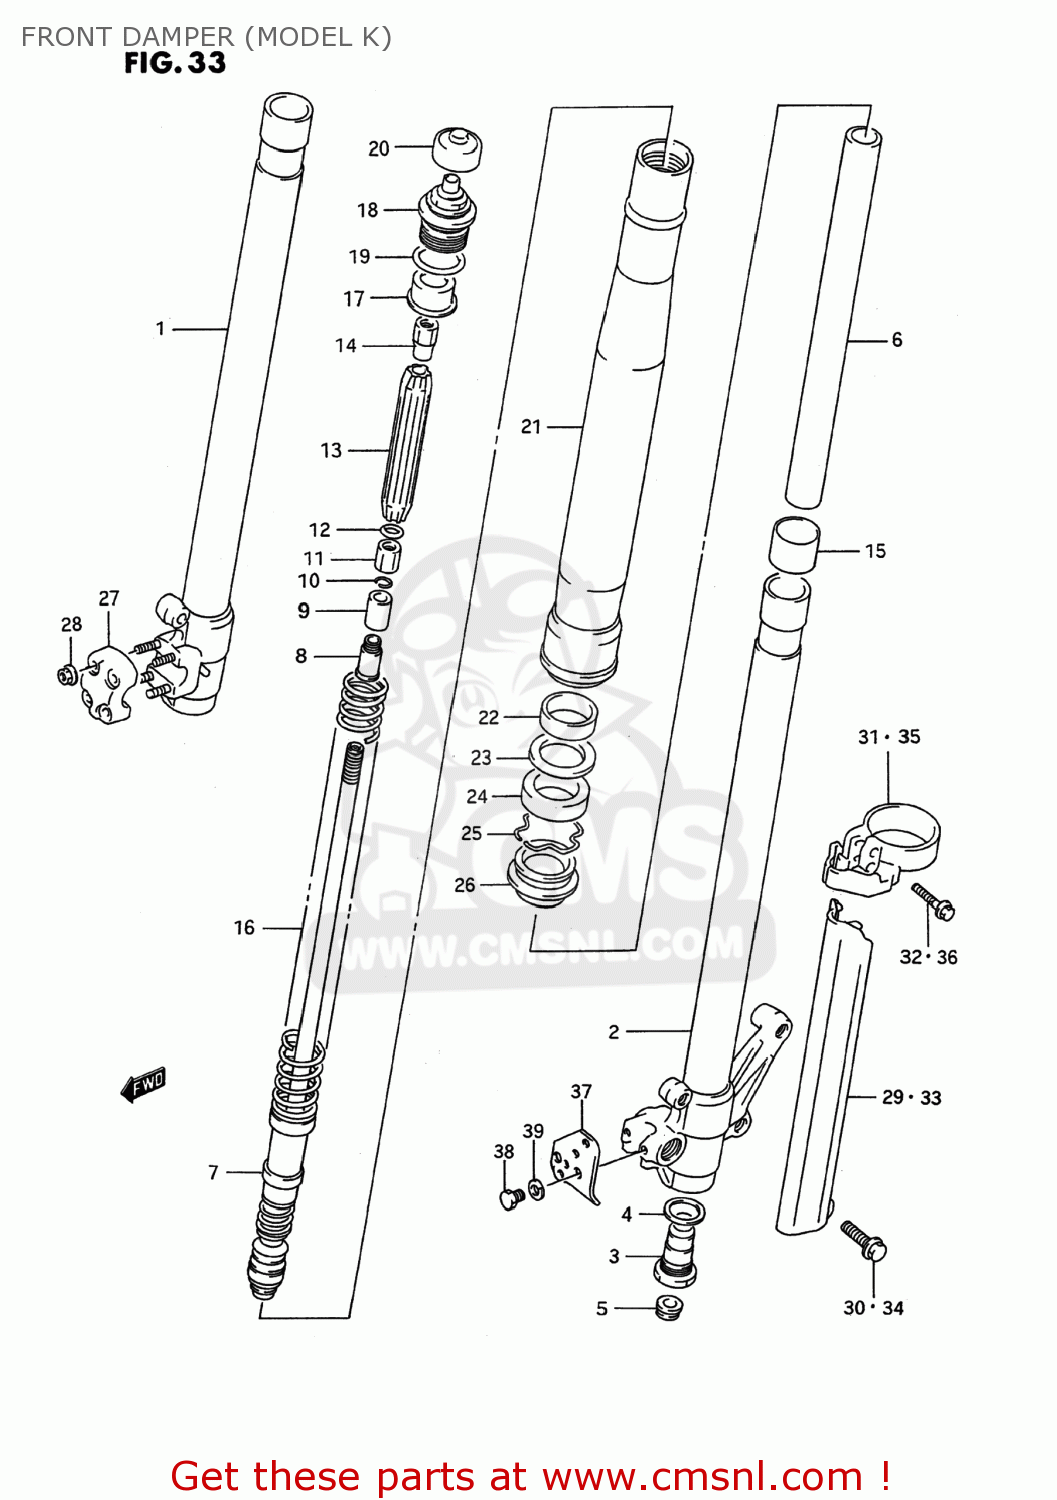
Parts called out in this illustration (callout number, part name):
1	TUBE,INNER,RIGHT
2	TUBE,INNER,LEFT
3	BASE,VALVE ASSEMBLY
4	GASKET (NAS)
5	CAP,RUBBER
6	CYLINDER
7	ROD ASSEMBLY,PISTON
8	HOLDER,PIECE
9	PIECE,OIL LOCK
10	RING,SNAP
11	NUT
12	O-RING
13	GUIDE,SPRING
14	NUT,PISTON ROD
15	PISTON
16	SPRING
17	GUIDE,SPRING
18	CAP
19	O RING
20	CAP
21	TUBE,OUTER
22	METAL,SLIDE
23	WASHER,FORK OIL SEAL
24	OIL SEAL,FRONT FORK
25	RING,OIL SEAL STOPPER
26	SEAL,DUST
27	HOLDER,AXLE
28	NUT
29	PROTECTOR,R
30	BOLT
31	HOLDER
32	BOLT, GUIDE
33	PROTECTOR,L
34	BOLT
35	GUIDE
36	BOLT, GUIDE
37	CLAMP,FRONT BRAKE HOSE
38	BOLT 5X10
39	LOCK WASHER
